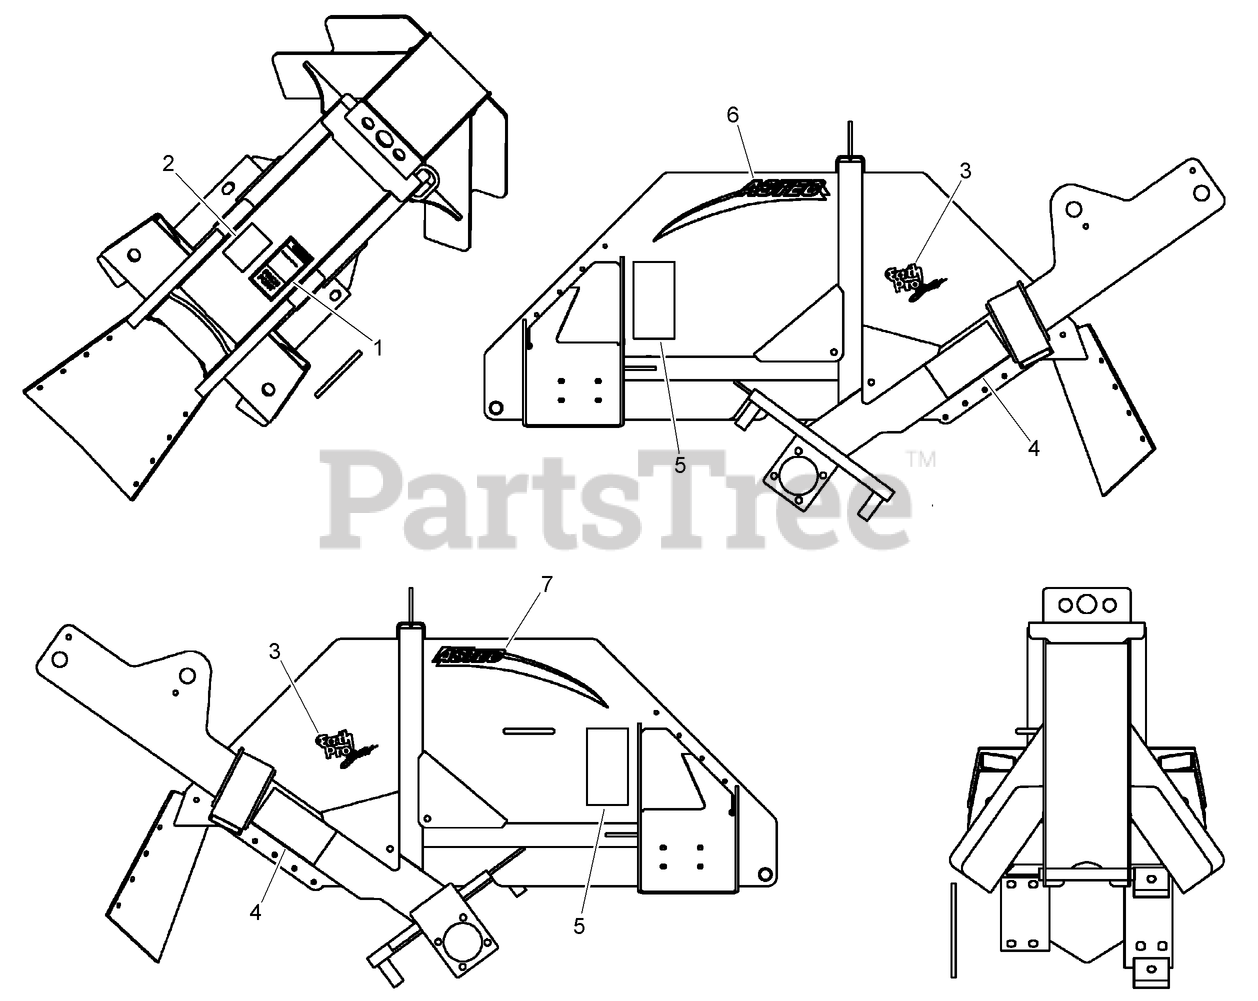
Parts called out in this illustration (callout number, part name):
1	LABEL - Pinch Point
2	DECAL - Warning, General Operation
3	DECAL - Earth Pro, Small
4	DECAL - Danger, Tren Entangle Hazard
5	DECAL - Wheel Hazard
6	DECAL - Astec
7	DECAL - Astec
